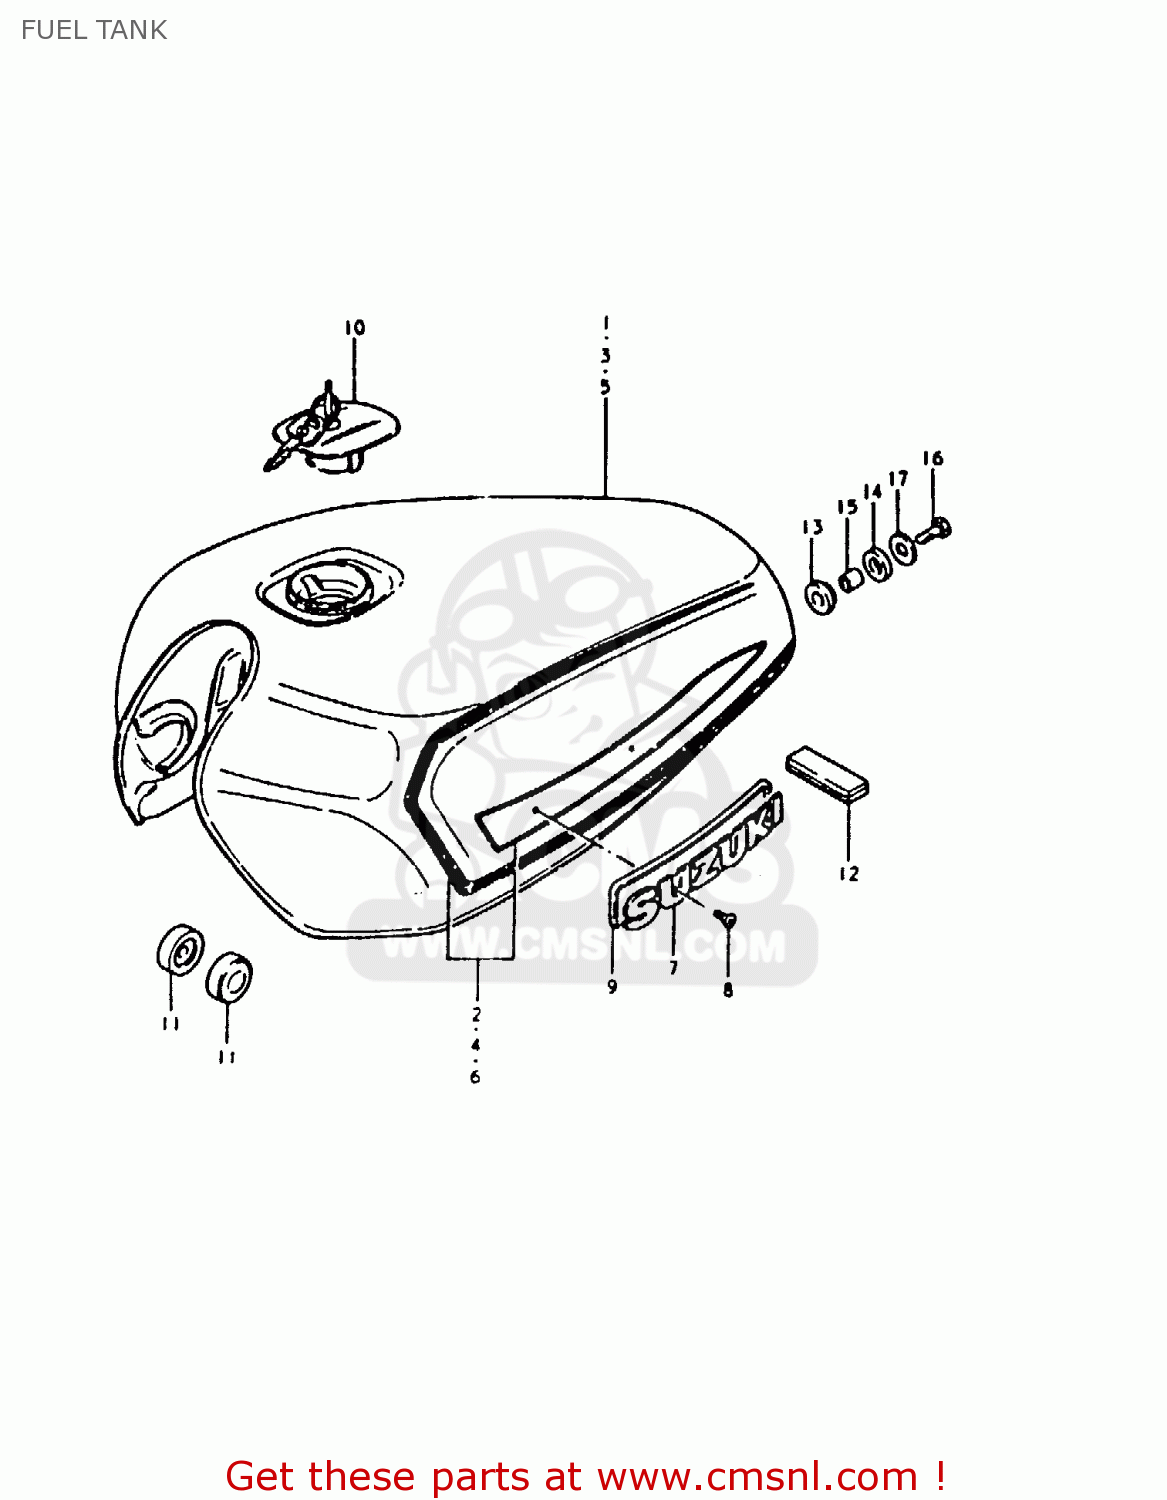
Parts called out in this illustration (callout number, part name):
1	TANK, FUEL (RED)
2	TAPE SET
3	TANK, FUEL (BLUE)
4	TAPE SET
5	TANK, FUEL (BLACK)
6	TAPE SET
7	EMBLEM,FUEL TANK
8	SCREW 3X6
10	CAP SET,FUEL TANK
11	CUSHION
12	CUSHION
13	CUSHION
14	CUSHION
15	SPACER(8.5X12X19)
16	BOLT (8X30)
17	WASHER (8.5X29X1.6)
